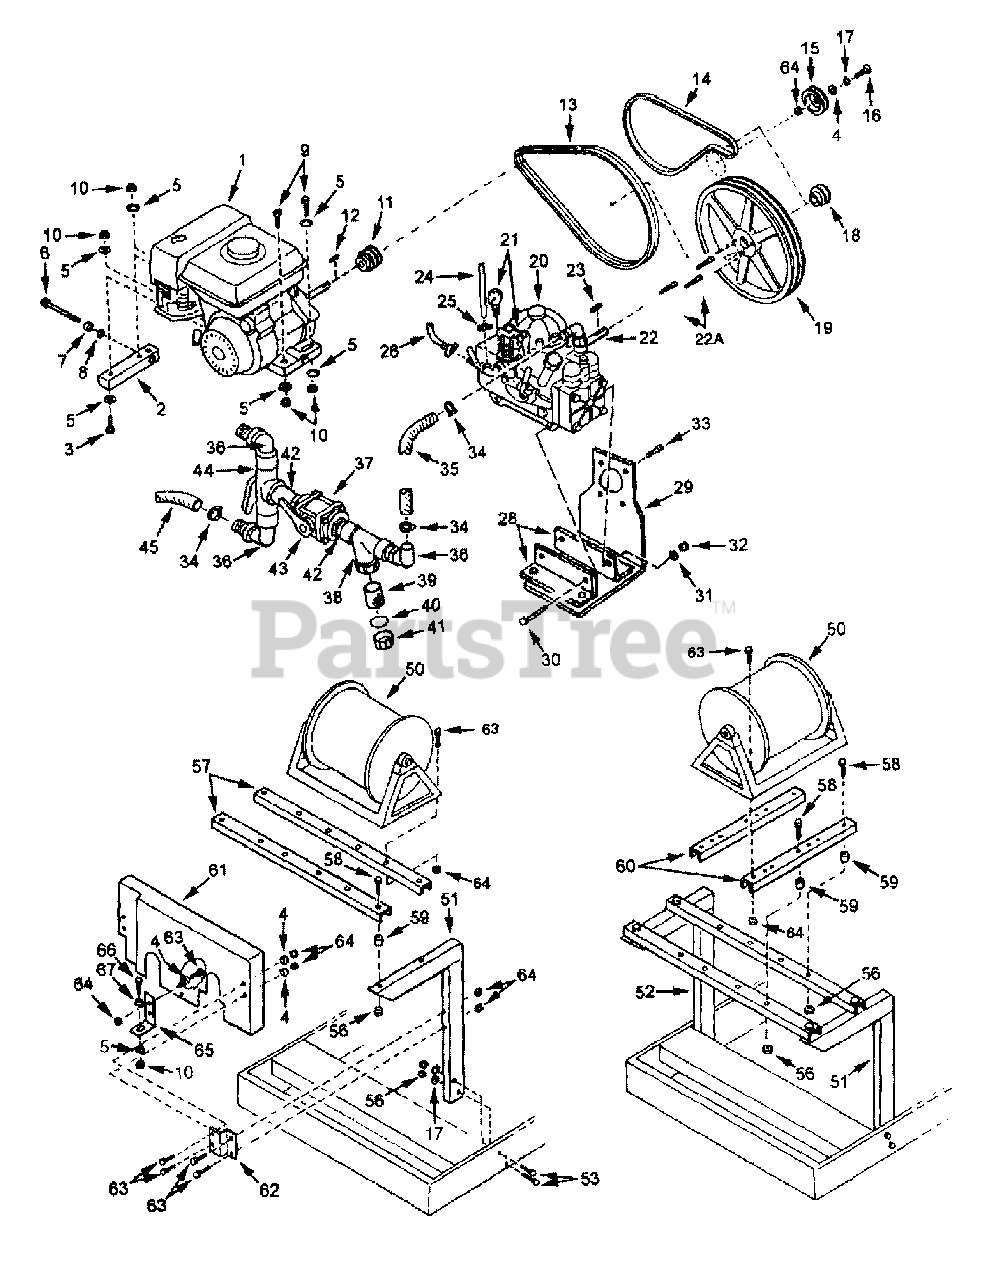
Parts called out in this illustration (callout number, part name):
1	Engine, 8.0-HP Kawasaki
2	Bar, Belt Tensioning
3	Cap Screw, 5/16-18 x 2-3/4
4	Washer, Flat 3/8
5	Flat Washer, 5/16 SAE
6	Cap Screw, 5/8-11 x 9-1/2 Hex Hd.
7	Spacer
8	Flat Washer, 5/8
9	Cap Screw, 5/16-18 x 1-1/2
10	Hex Nut, 5/16-18 Nylock
11	Sheave
12	Key, 3/16 x 3/16 x 1
13	Belt, Pump Drive
14	Belt, Agitator Drive
15	Idler Pulley, Flat
16	Carriage Bolt, 3/8-16 x 2
17	Flat Washer, 1/2 USS
18	Sheave Small
19	Sheave Large
20	Pump, Twin-Piston, D-50
21	Control Unit, Pump
22	Pump Shaft, with Bolt Flange
22A	Cap Screw, Socket Head
22A	Lock Washer
23	Key, 1/4 x 1/4 x 2-1/2
24	Hose, 5/8" PVC (Sold per foot)
25	O-Clamp, 1" for 5/8" Hose
26	Hose Assembly, Pump to Reel
28	Pump Base, D-50 Pump
29	Pump Bracket
30	Cap Screw, 7/16-14 x 2-1/2 Hex Hd.
31	Lock Washer, 7/16
32	Hex Nut, 7/16-14
33	Cap Screw (Part of Pump)
34	Hose Clamp, Wormgear, 1-1/4 - 1/1/2 4
35	Hose, 1-1/4" (D-50) (Sold per ft.)
36	Elbow, 90°, 1" HB (D-30)
37	Manifold
38	Strainer Assembly
39	Screen, 20 Mesh, S.S.
40	Gasket
41	Strainer Bowl
42	Nipple, 1-1/4
43	Ball Valve
44	3 Way Valve, 1-1/4" HB
45	Hose, 1-1/4" Spiraflex (Sold per foot)
50	Hose Reel
51	Bracket, Hose Reel Mount, R.H.
52	Bracket, Hose Reel Mount, L.H.
53	Cap Screw, 1/2-13 x 1-1/2 Hex Hd.
56	Hex Nut, 1/2-13, Nylock
57	Cross Bar
58	Cap Screw, 1/2-13 x 2 Hex Hd.
59	Spacer, Cross Bar
60	Channel, Pick-up Mount
61	Belt Cover, Fiberglass
62	Mount, Belt Cover, R.H.
62	Mount, Belt Cover, L.H.
63	Cap Screw, 3/8-16 x 1 Hex Hd.
64	Hex Nut, 3/8-16, Nylock
65	Support, Belt Cover
66	Cap Screw, 5/16-18 x 1 Hex Hd.
